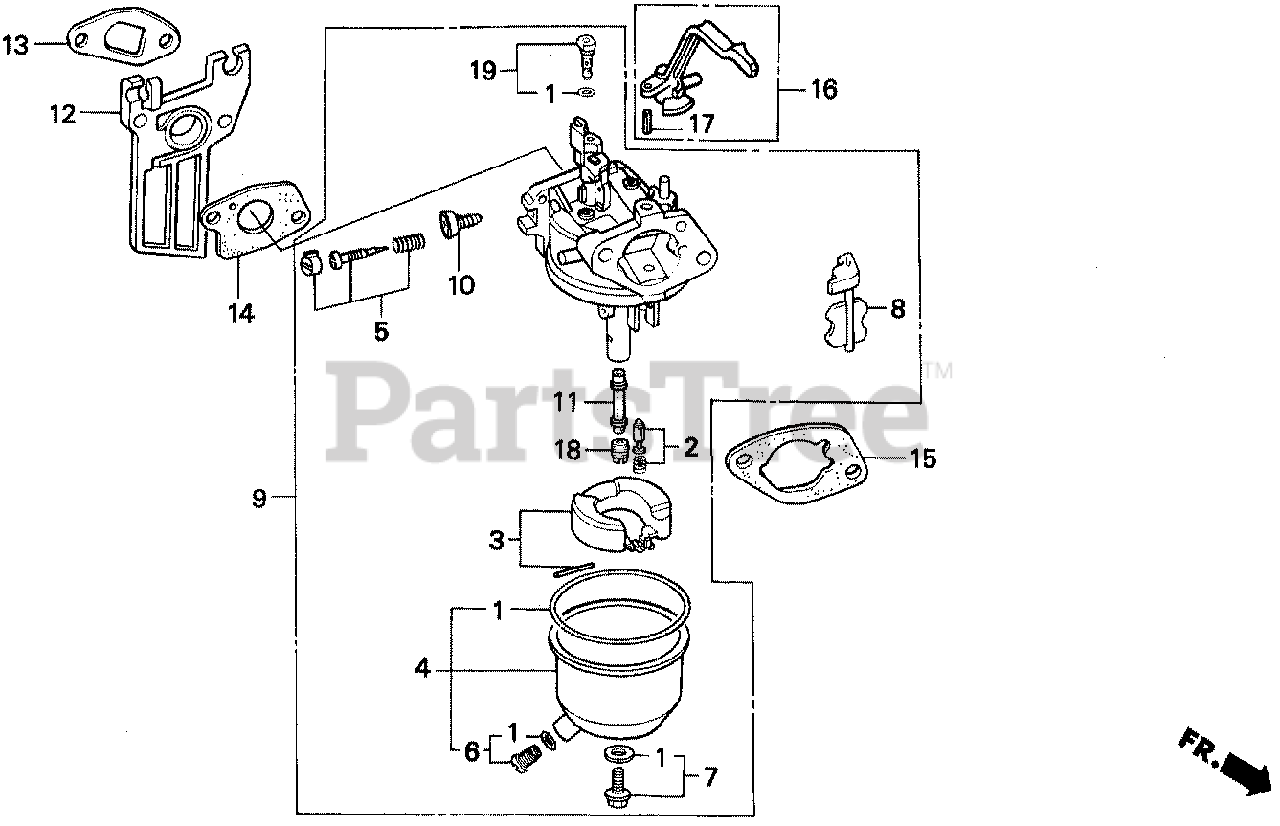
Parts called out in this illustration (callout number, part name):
1	GASKET SET
2	VALVE SET, FLOAT
3	FLOAT SET
4	CHAMBER SET, FLOAT
5	SCREW SET
6	SCREW SET, DRAIN
7	SCREW SET B
8	CHOKE SET
9	CARBURETOR ASSY. (BE67A B)
10	SCREW, THROTTLE STOP
11	NOZZLE, MAIN
12	INSULATOR, CARBURETOR
13	GASKET, INSULATOR
14	GASKET, CARBURETOR
15	GASKET, AIR CLEANER
16	LEVER, CHOKE
17	PIN, SPRING (2X12)
18	JET, MAIN (#70)
18	JET, MAIN (#72)
18	JET, MAIN (#75)
19	JET SET, PILOT (#35)
